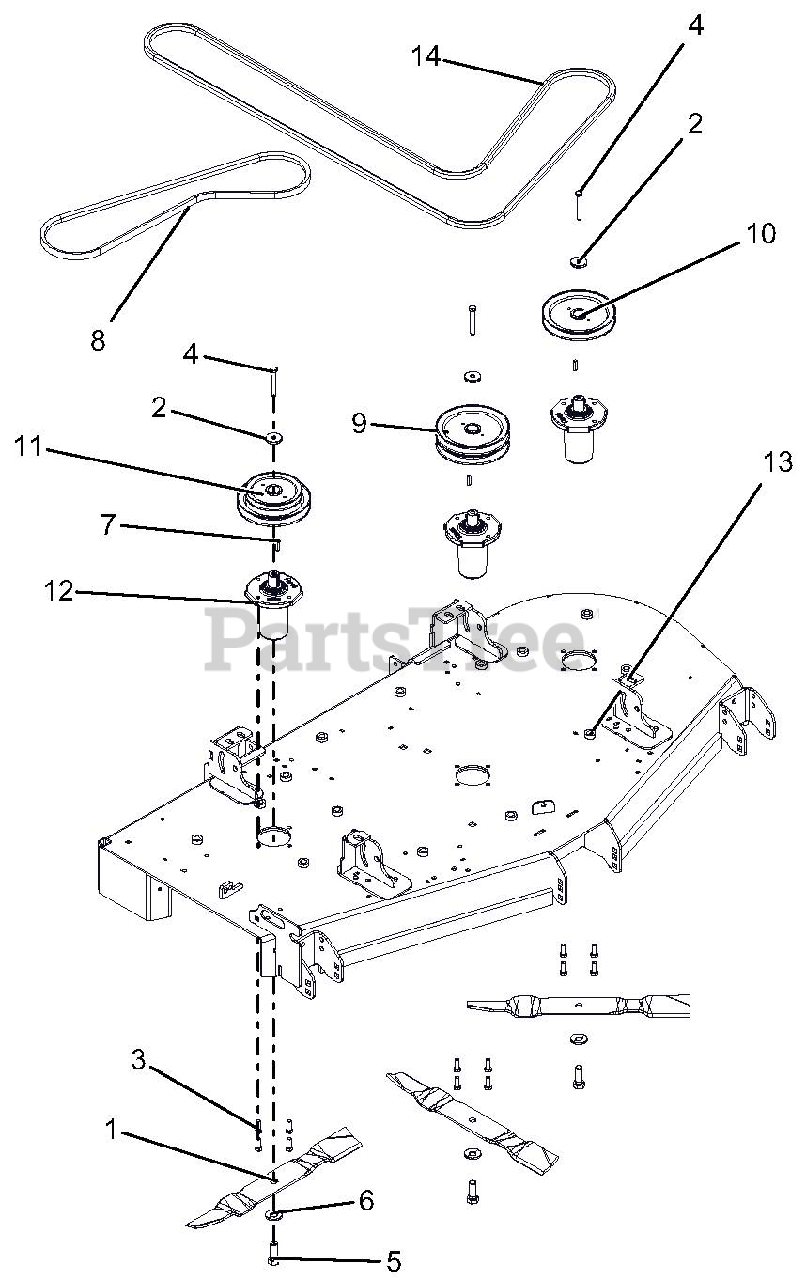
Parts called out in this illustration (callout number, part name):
1	BLADE, MULCH
2	RETAINER, SHEAVE SPINDLE
3	BLT-HEX .38-16X1.00 GR5 YWZC EP30
4	BLT-HEX .38-16X2.75 GR8 YWZC
5	BLT, HEX .62-18X1.75 GR8 YWZC
6	WSHR, BLVL .63X1.625X.14
7	KEY-SQ .250X.250X1.00 RC 40-50
8	BELT, B 63.00 RAW COGGED
9	PULLEY, DOUBLE 1"ID X 6.75"OD
10	PULLEY, V-1" ID X 6.75" OD
11	PULLEY, DOUBLE -1" ID X 6.75" & 5.25" OD
12	SERVICE, ASM SPINDLE- DUCTILE
13	WLDMT, 60" SIDE DISCH DECK
14	BELT, BB 118.00 WRAPPED HEX
